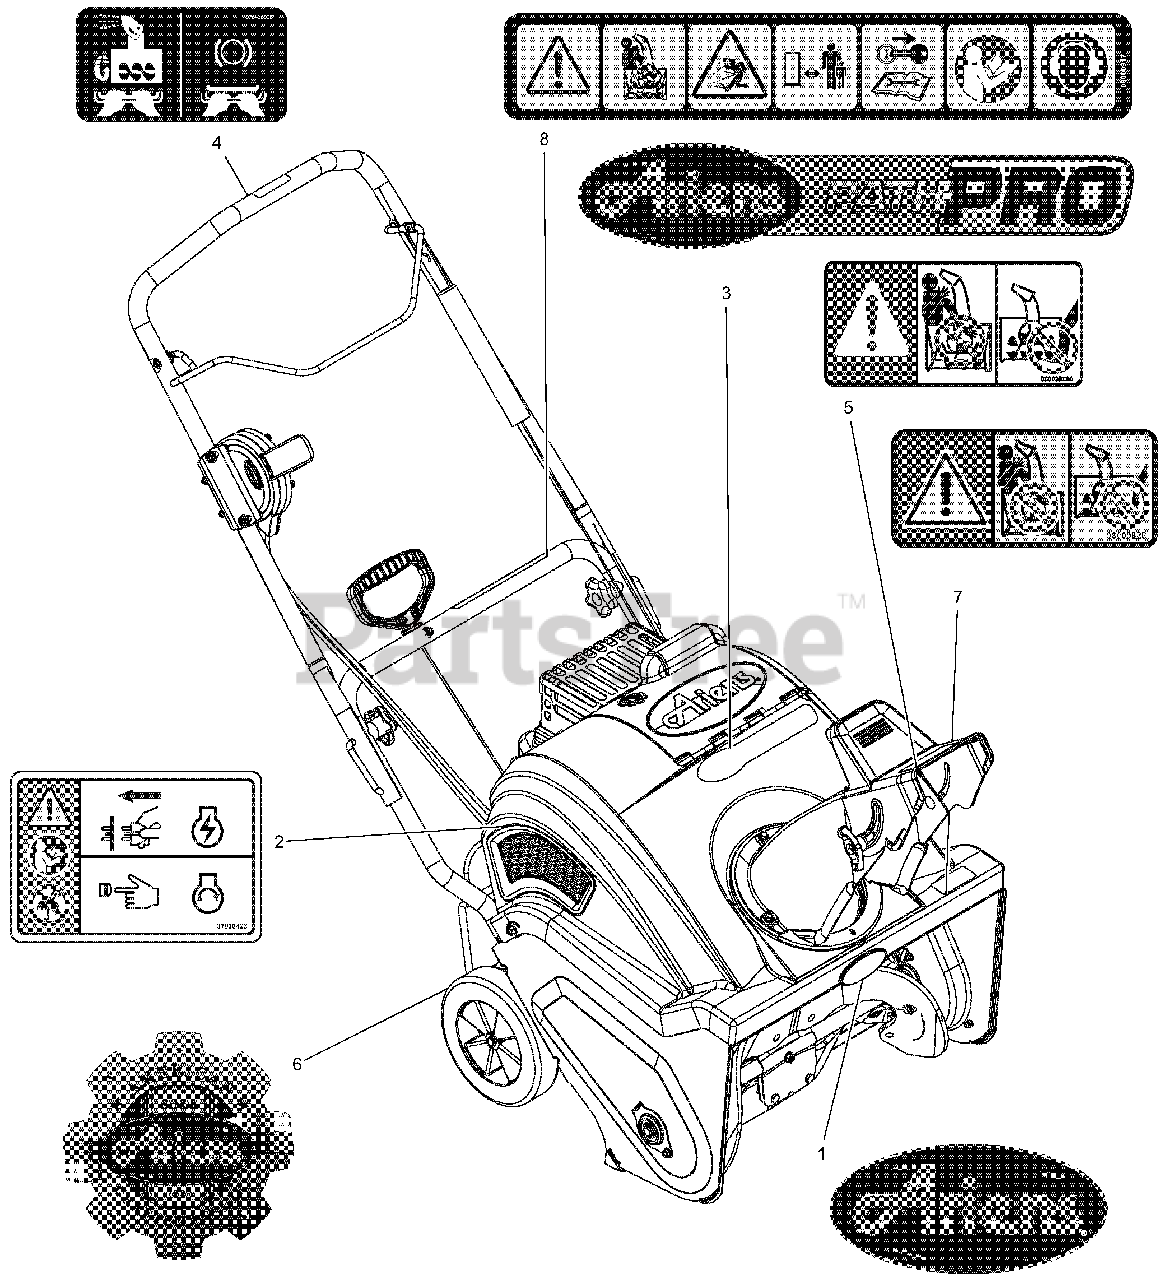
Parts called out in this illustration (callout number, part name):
1	DECAL. ARIENS DOMED JEWEL
2	DECAL, ELECTRIC START
3	DECAL, BRAND - SINGLE STAGE
4	DECAL-AUGER/IMPELLER BAIL
5	DECAL, DANGER
6	DECAL, ARIENS HERITAGE-SMALL
7	DECAL, DANGER SINGLE STAGE
8	DECAL, WARNING
